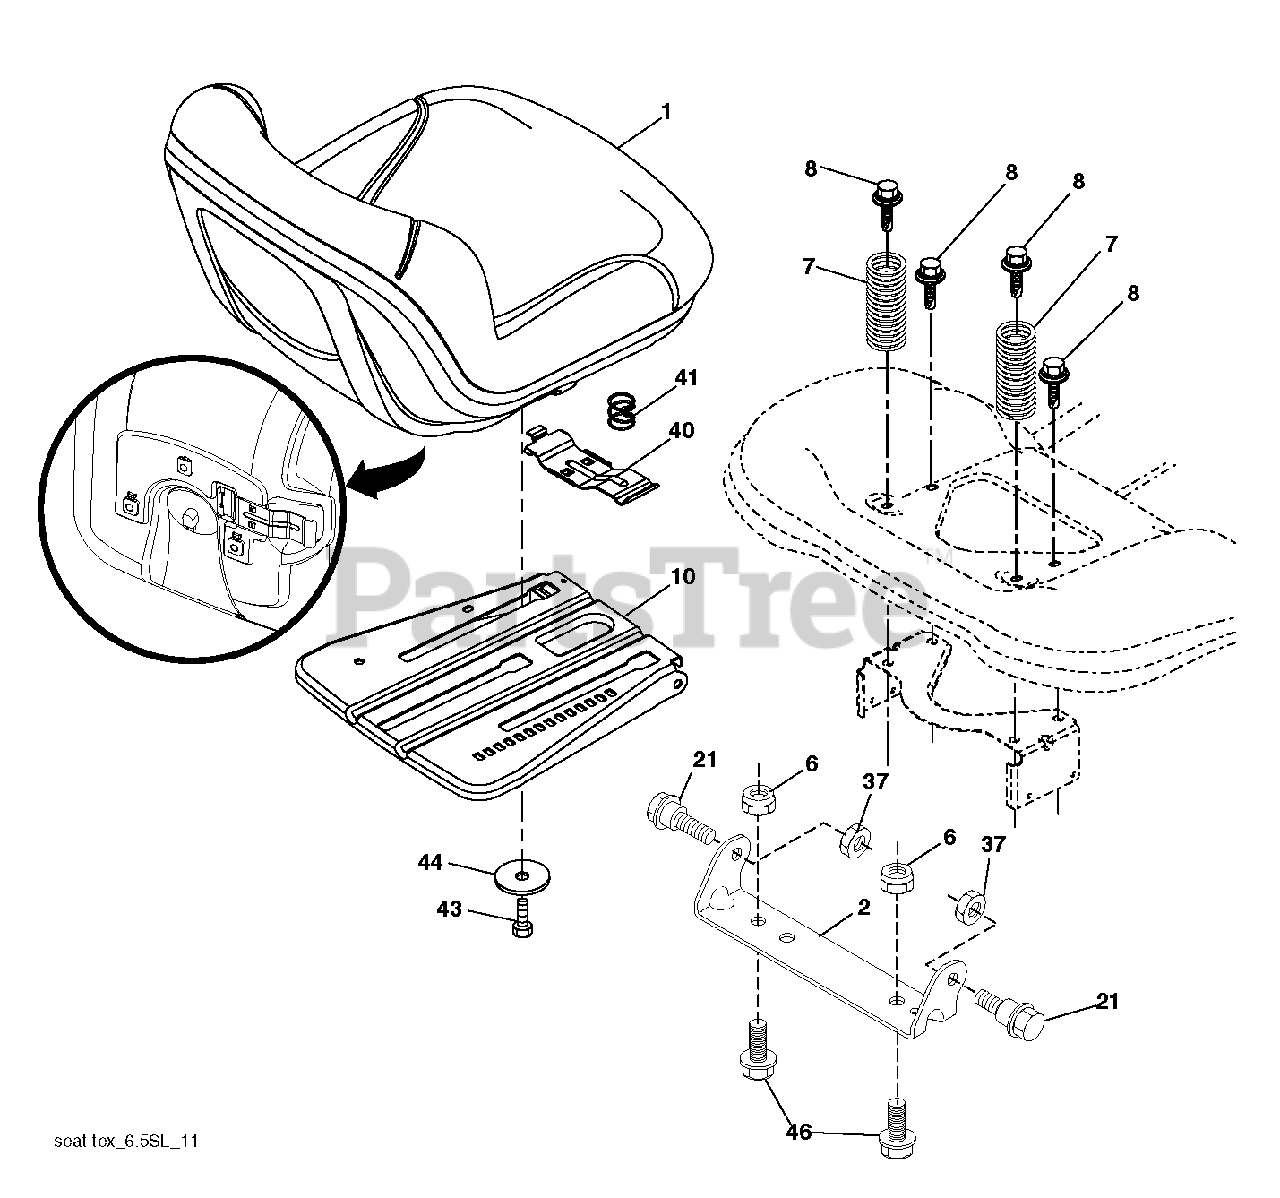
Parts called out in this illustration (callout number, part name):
1	SEAT.TH150.MS498.GRY.HUSQ.TEX
2	BRKT.PIVOT.FENDER
6	NUT
7	SPRING.COMPRESSION.SEAT.BLACK
8	BOLT, 5/16-18 X 1 3/4
10	PAN.ASM.SEAT.3PT
21	BOLT.5/16-18X5/8.SHOULDER
37	NUT.71038.31-18.HEX.NYLOCK
40	HANDLE.SLIDE.SEAT.TEX.BLACK
41	SPRING.LATCH.SEAT.TEX
44	WASHER 13/32 X 2-3/8 X 12GA
46	BOLT.3/8-16X1;1.25OD.WSHR.SEMS
